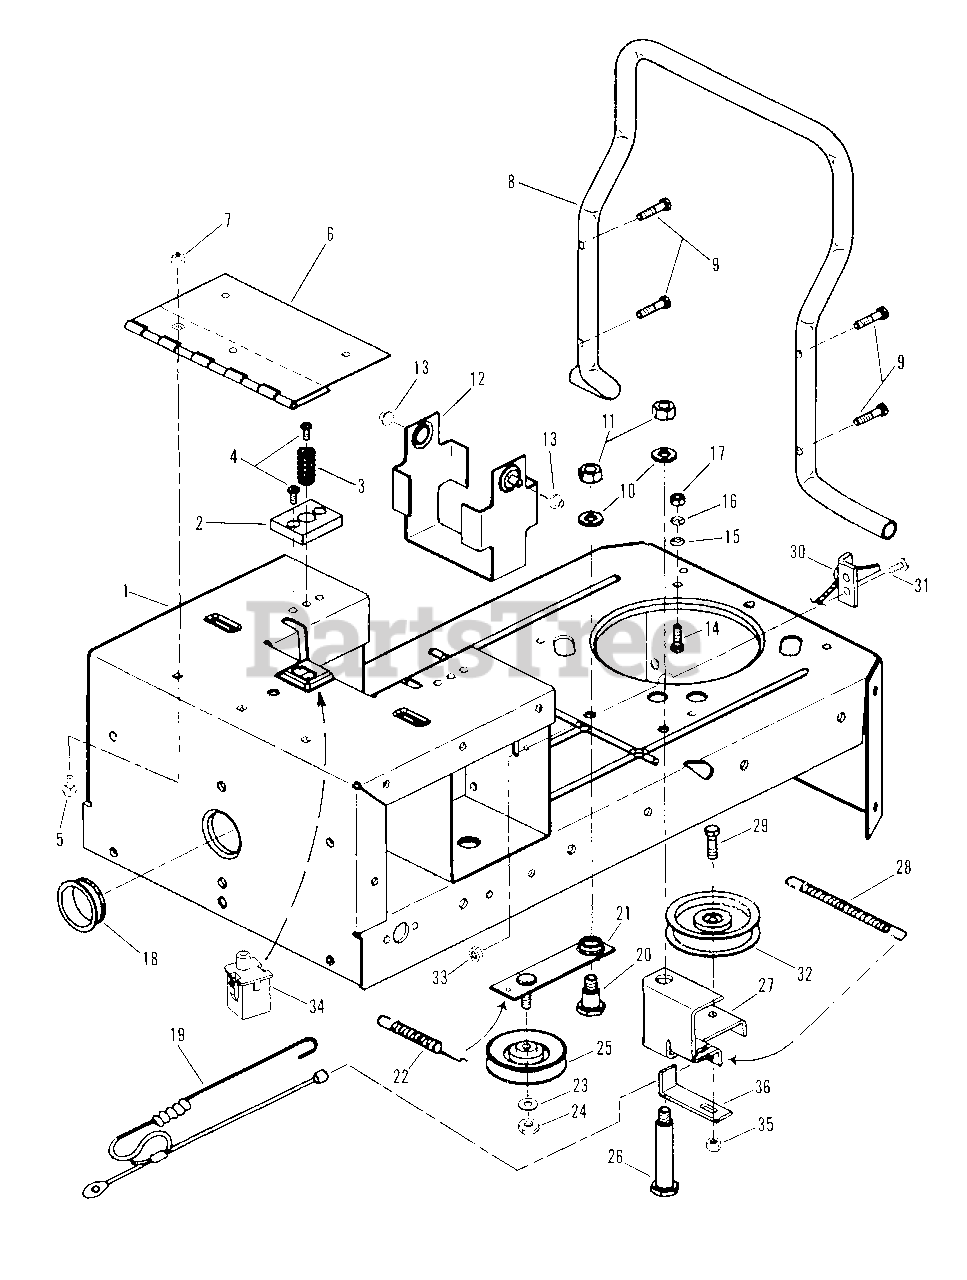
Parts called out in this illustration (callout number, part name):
1	FRAME, Rear
2	CUSHION, Seat Support
3	SPRING, Seat Support
4	SCREW, 1/4-20 x 5/8" Pan Head, Self-Tapping
5	BOLT, 5/16-18 x 1/2" Carriage, Grade 5
6	HINGE, Seat
7	NUT, 5/16-18 Hex Flange Lock, Grade 5
8	BUMPER, Rear
9	SCREW, 5/16-18 x 1-1/2" Hex Washer Head, Self-Tapping
10	WASHER, 1/2" Flat
11	NUT, 1/2-13 Hex, Grade B
12	BRACKET, Battery
13	BUSHING
14	SCREW, 5/16-24 x 1" Hex Head Cap
15	RETAINER, 5/16 Bolt
16	WASHER, 5/16 Split Lock
17	NUT, 5/16-24 Hex, Grade 5
18	GROMMET
19	CABLE, Brake/Clutch
20	BOLT, 1/2-13 x 5/8" Thread, .75 x .788 Shoulder
21	IDLER ARM, Primary
22	SPRING, Blade/Clutch 3/4" x 5.5"
23	WASHER, 3/8" Flat
24	NUT, 3/8-16 Hex Center Lock, Grade 5
25	PULLEY, Idler V 3.30 HA
26	BOLT, 1/2-13 x 5/8" Thread, .75 x 3.23 Shoulder
27	BRACKET, Hydraulic Idler
28	SPRING, 3/4" x 10" Extension
29	SCREW, 5/16-18 x 1" Hex Head Cap, Grade 5
30	CABLE, Hydro Release Valve
31	SCREW, #10-32 x 5/8" Hex Washer Head, Machine
32	IDLER, 4.12 Flat
33	NUT, #10-32 Hex Nyloc
34	SWITCH, Seat
35	NUT, 5/16-18 Hex Center Lock
36	GUIDE, Belt
